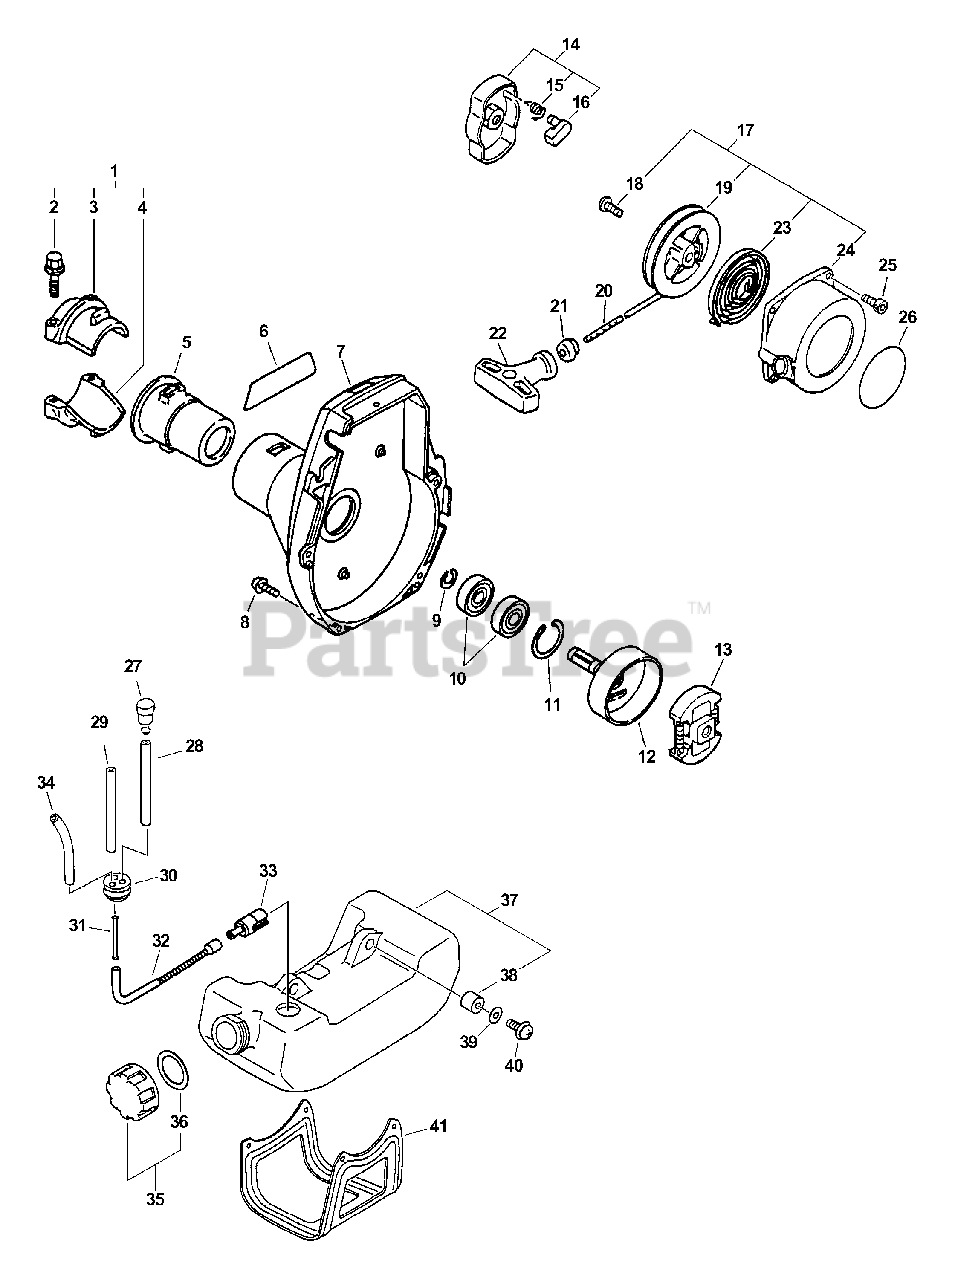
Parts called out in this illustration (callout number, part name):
1	RETAINER KIT
2	BOLT - 5×25
3	HOLDER, MAIN PIPE - UPPER
4	HOLDER - LOWER
5	CUSHION Ø25
6	LABEL, SHC-2400
7	COVER ASSY, FAN
8	BOLT 4×16
9	RING, RETAINING - 12
10	BEARING, BALL 6001
11	RING, SNAP 28
12	DRUM, CLUTCH
13	CLUTCH ASSY
14	PAWL ASSY, STARTER
15	SPRING, RETURN
16	PAWL, STARTER - BLACK
17	STARTER ASSY, RECOIL
18	SCREW
19	REEL, ROPE
20	ROPE, STARTER 3.0×1000
21	GUIDE, ROPE
22	GRIP, STARTER
23	SPRING, RECOIL
24	CASE, RECOIL STARTER
25	BOLT 4×16
26	LABEL, ECHO
27	VENT ASSY
28	PIPE, FUEL 3x-5x-70 BLACK
29	PIPE, FUEL 3x-5x-70 BLACK
30	GROMMET, FUEL
31	CONNECTOR, PIPE
32	PIPE, FUEL - CORRUGATED
33	FILTER, FUEL
34	PIPE, FUEL RETURN 3×6×90 MM CLEAR
35	CAP ASSY, FUEL
36	GASKET, FUEL CAP
37	TANK, FUEL
38	SPACER 6.2×7.8×6
39	WASHER 5.5×12×0.8
40	SCREW 5×16
41	GUARD, FUEL TANK
